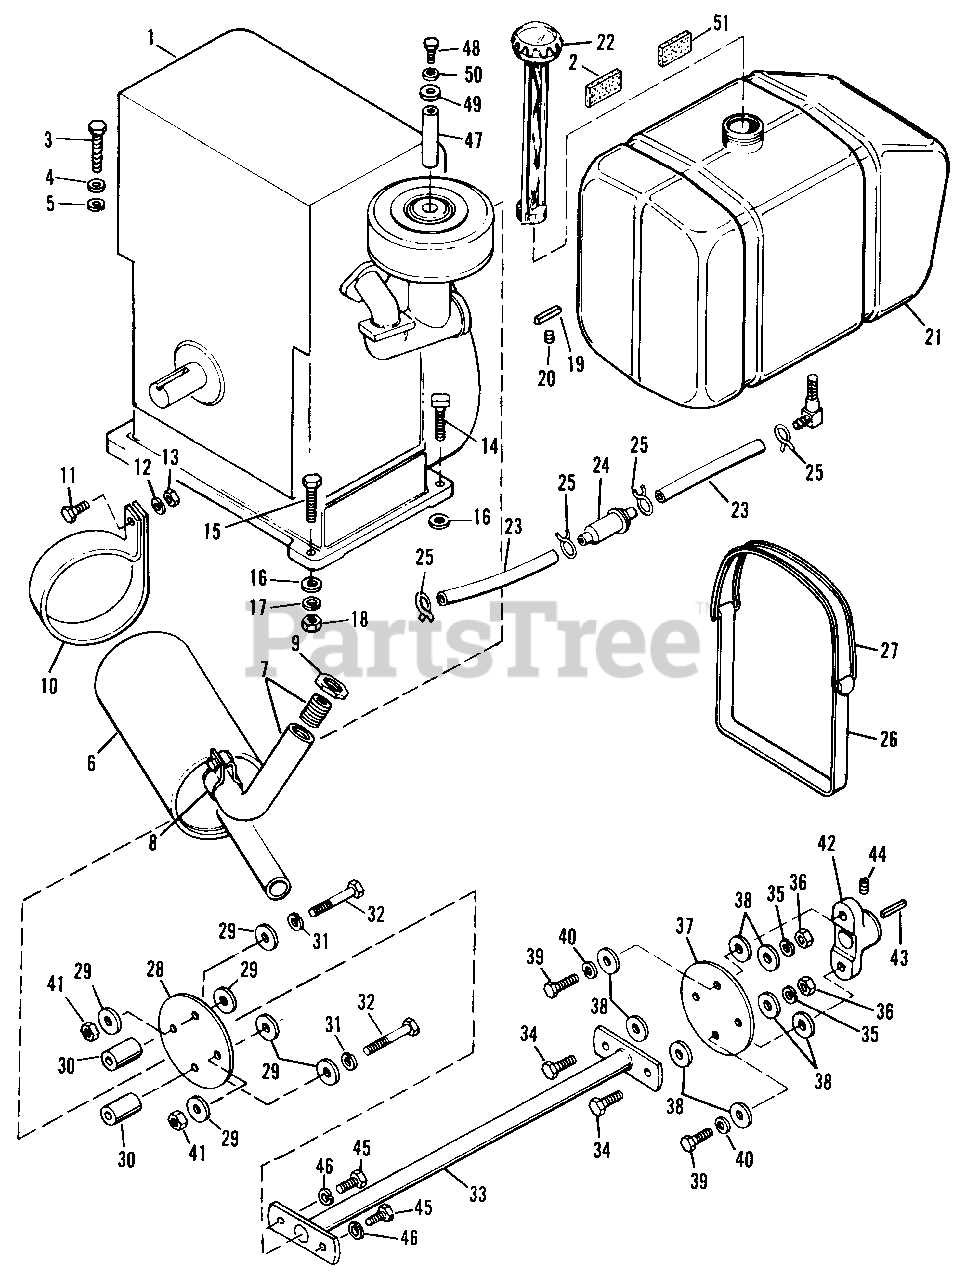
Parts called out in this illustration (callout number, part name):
2	Pad, Fuel Tank
3	Hex Capscrew, 5/16"-18 x 2"
4	Plain Washer, 5/16"
5	Lockwasher, 5/16"
6	Muffler, Exhaust
7	Elbow & Nipple Assembly
8	Muffler Clamp
10	Strap, Muffler
11	Hex Capscrew, 5/16"-18 N.C. x 5/8"
12	Lockwasher, 5/16"
13	Full Hex Nut, 5/16"-18 N.C.
14	Rec't. Head Screw, 3/8"-16 N.C. x 1-5/16"
15	Hex Capscrew, 3/8"-16 N.C. x 1-1/2"
16	Plain Washer, 318" Std.
17	Lockwasher, 3/8"
18	Full Hex Nut, 3/8"-16 N.C.
19	KEY, Hi-Pro
20	Cup Pt. Socket Head Set Screw, 5/16"-18 N.C. x 3/8"
21	Tank, Fuel
22	Cap, Fuel Tank
23	Hose, Fuel, Flexible
24	Fuel Filter
25	Clamp, Hose
26	Strap, Tank
27	Strap, Fuel Tank
29	Washer, Special
30	Bearing, Pivot Block
31	Lockwasher, 3/8"
32	Hex Capscrew, 3/8"-16 x 2-1/4"
33	Shaft Assy., Drive
34	Hex Capscrew, 3/8"-16 x 1-1/8"
35	Lockwasher, 3/8"
36	Full Hex Nut, 3/8"-16
38	Washer, Special
39	Hex Capscrew, 3/8"-16 N.C. x 1-1/8"
40	Lockwasher, 3/8"
41	Full Hex Nut, 3/8"-16 N.C.
42	Flange, Drive Shaft
43	Key, Drive Shaft
44	Cup Pt. Socket Head Set Screw, 3/8"-24 N.F. x 3/8"
45	Hex Capscrew, 3/8"-16 N.C. x 1-1/8"
46	Lockwasher, 3/8"
47	Air Cleaner Spacer
48	Hex Capscrew, 1/4"-20 N.C. x 5/8"
49	Plain Washer, 1/4"
50	Lockwasher, 1/4"
51	Gasket, Felt
